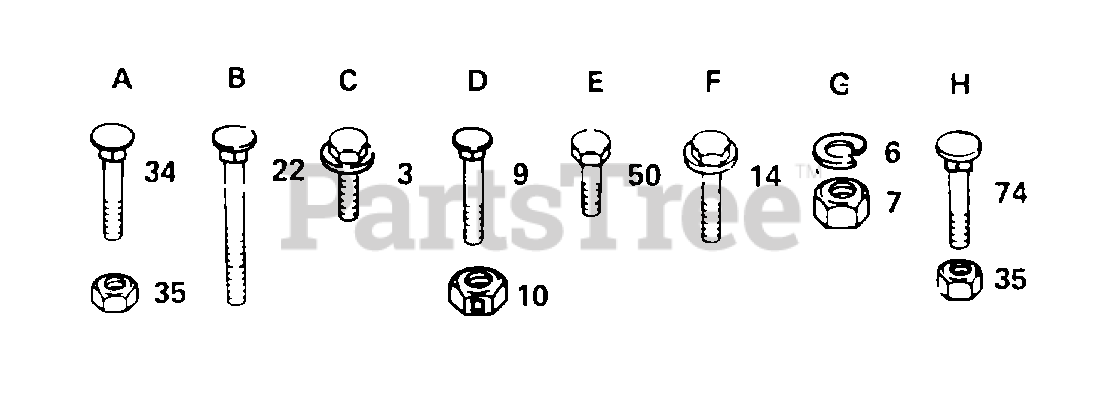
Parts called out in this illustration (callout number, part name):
3	SCREW LT
6	LOCKWASHER
7	NUT.HEX.5/16-18
9	BOLT
14	SCREW
22	BOLT
34	BOLT
50	BOLT
74	BOLT
